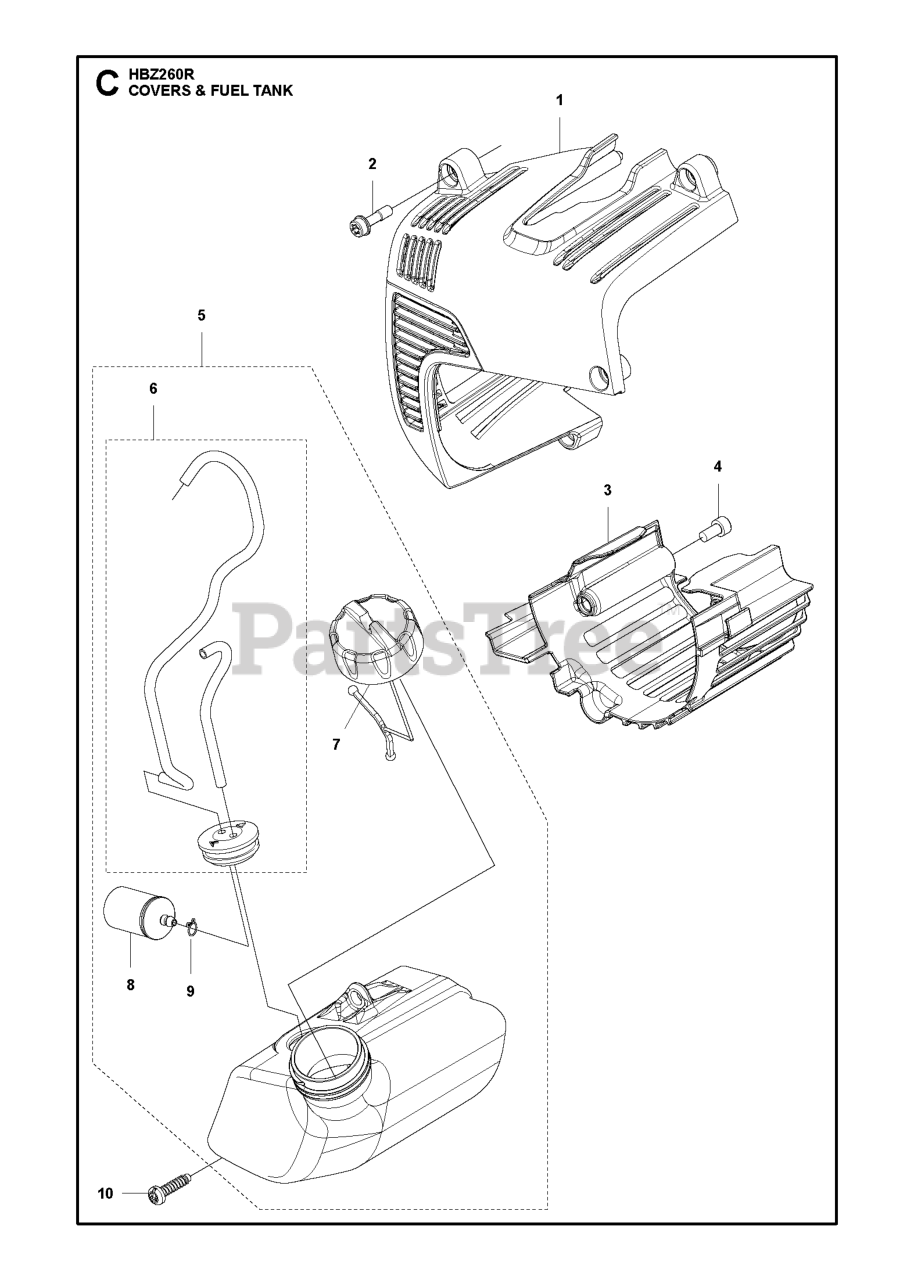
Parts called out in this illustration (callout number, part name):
1	ENGINE COVER
2	BOLT
3	PLATE MUFFLER BLACK
5	FUEL TANK ASSY EVP
6	HOSE ASSY EVP
7	TANK CAP
8	FUEL FILTER
9	CLIP
10	SCREW, TORX (RPLS T4970-52001)
